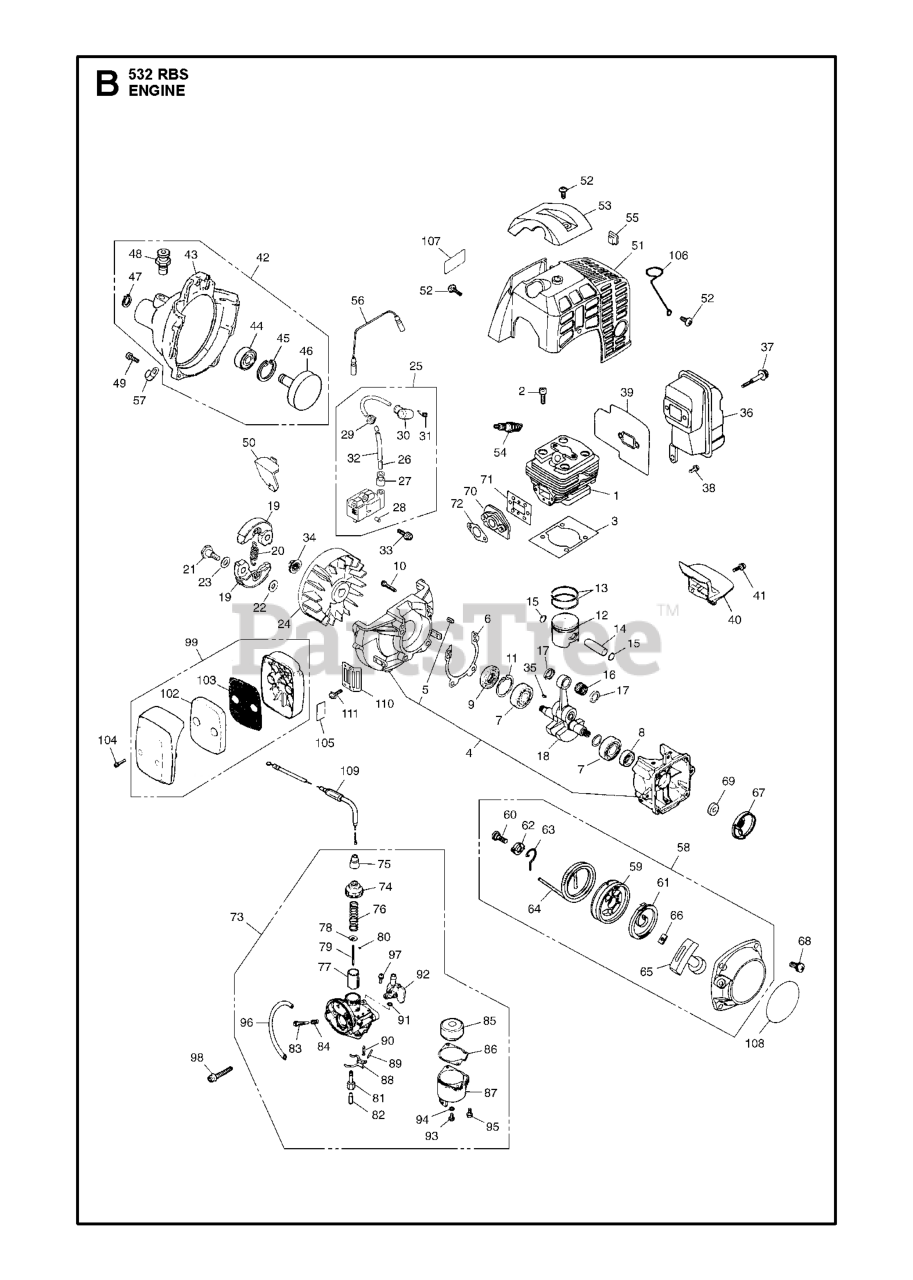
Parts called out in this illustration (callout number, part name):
13	PISTON RING
16	ROLLER BEARING
27	CAP
29	GROMMET
32	TUBE (RPLS 263072210)
34	NUT
37	BOLT, M5 x 60
40	PLATE.MUFFLER
54	SPARKPLUG.RCJ6Y
57	CLAMP
58	RECOIL ASSY
61	SPRING, SPIRAL
77	VALVE, THROTTLE
83	SCREW.ADJUST
90	VALVE.NEEDLE
